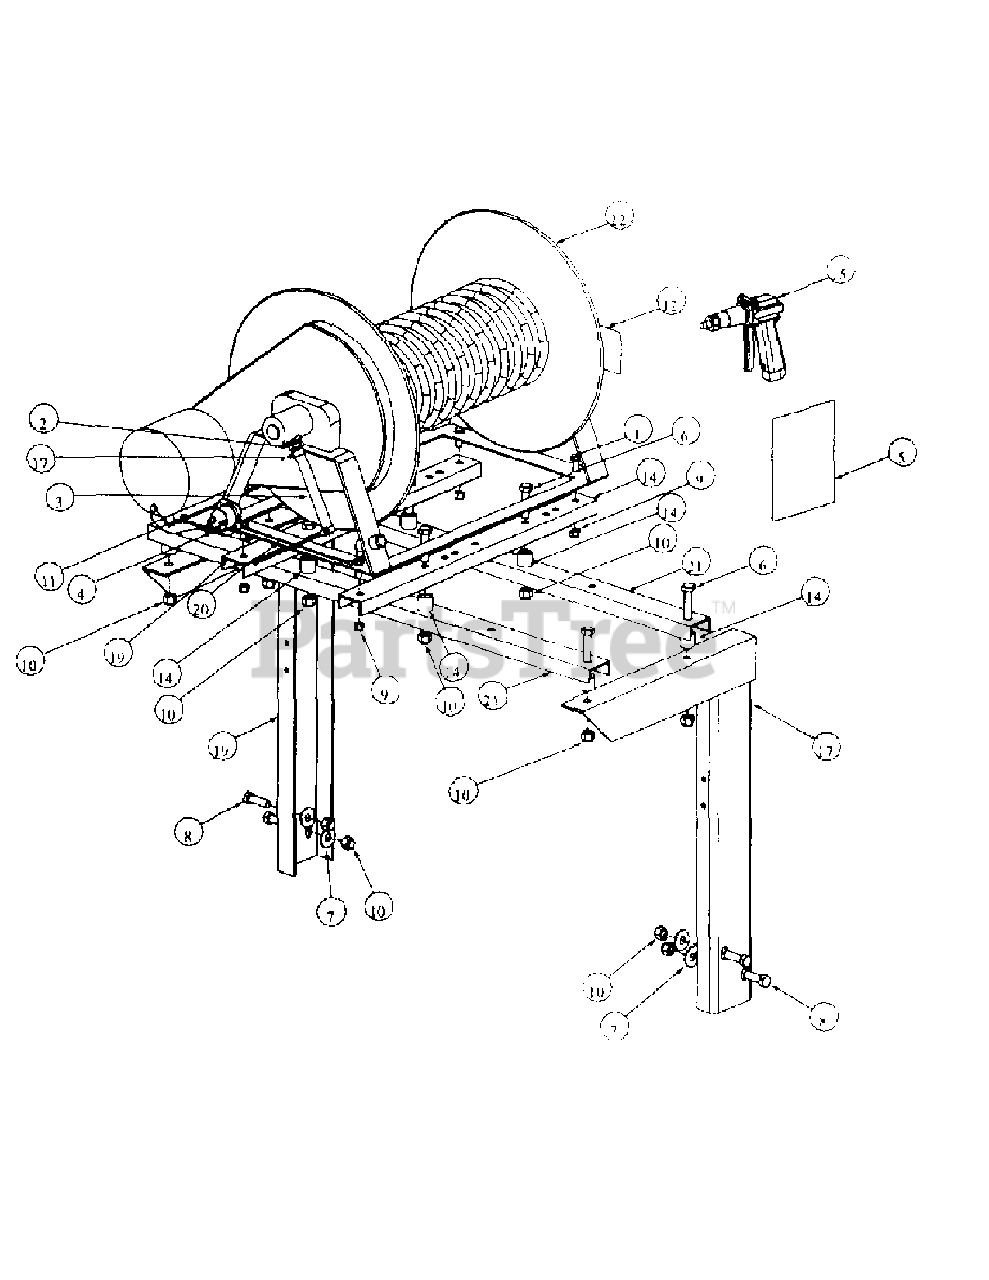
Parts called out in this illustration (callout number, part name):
1	HHCS, 3/8-16 x 1"
2	Hose Barb, 1/2NPT, 1/2
3	Hose, 112" by ft. (sold by the foot)
4	Terminal Ring, 3/8 x #8 Ga
5	Wiring Kit, Elec. Hose Reel
6	HHCS, 112-13, 2.00
7	Flat Washer, 1/2 USS
8	HHCS, 1/2-13, 1-1/2
9	Nut, Lock Nylon Insert, 3/8-16
10	Nut, Lock Nylon lnsert, 1/2-13
11	Cable, Tie, 3/16 x .05 x 7-1/2
12	Decal, Max Hose Length
14	Spacer Crossbar
15	Spray Gun
16	Hose Clamp, 1/2, 7/8
17	Bracket Assembly, RH Hose Reel
18	Bracket Assembly, LH Hose Reel
19	Channel, Pick-Up Mount Reel Support
20	Wiring Harness
21	Crossmember Hose Reel
